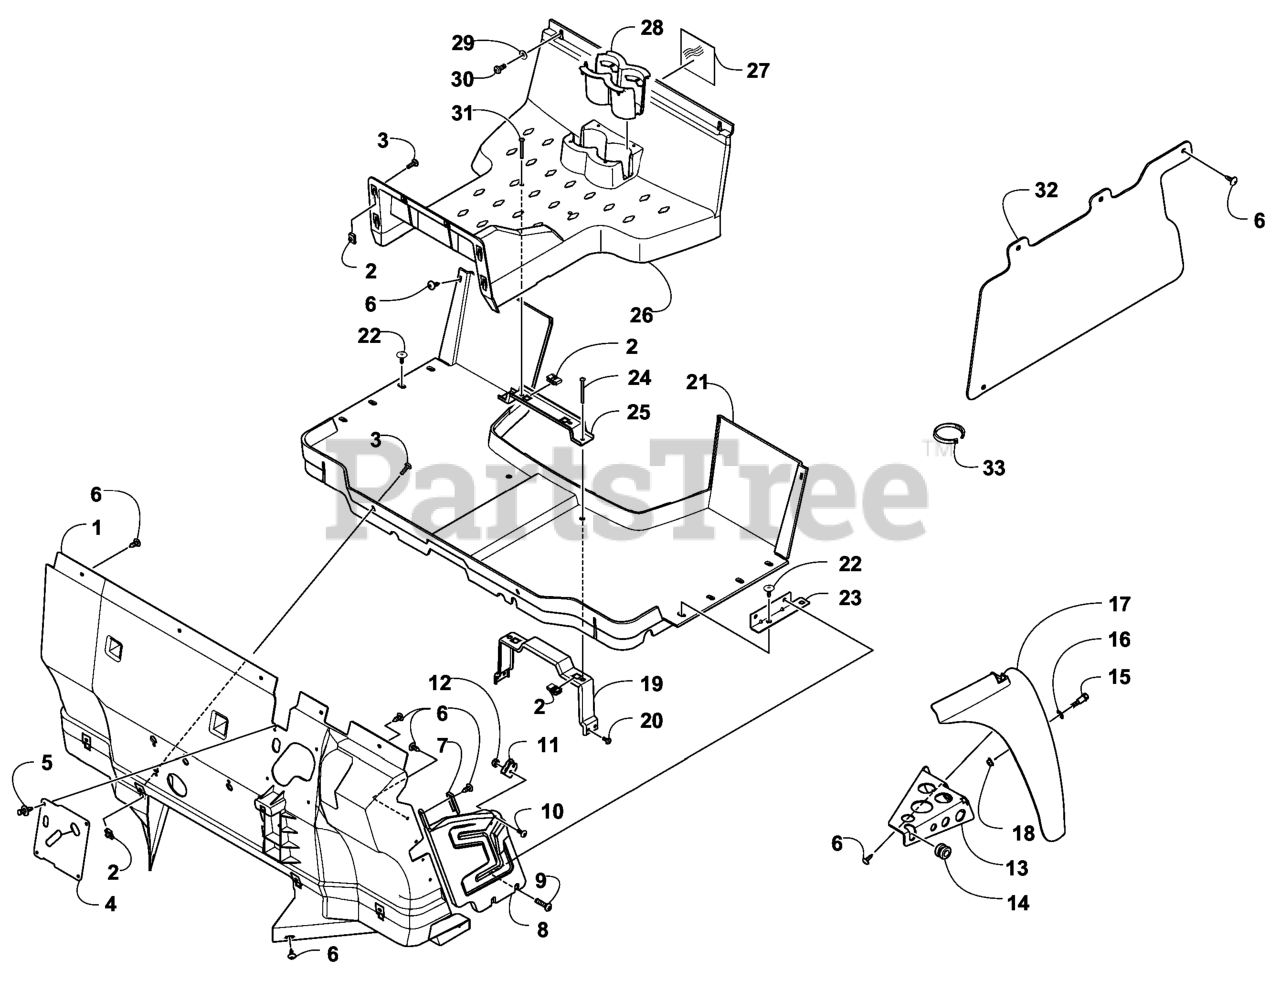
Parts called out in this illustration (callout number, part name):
1	PANEL-INNER FENDER
2	CLIP-U NUT
4	BOOT-STEERING
5	RIVET-PLASTIC, REINSTALLA
6	SCREW-TSTRH, SELFTAP
7	BRACKET-KICK PANEL
8	PANEL-SIDE KICK
9	SCREW-TSPNH
10	SCREW-TSPRH
11	TONGUE-BUCKLE
12	NUT-LOCK
13	BRACKET-SUPPORT, RH
13	BRACKET-SUPPORT, LH
14	GROMMET-GAUGE MOUNT
15	SCREW-HEX,DOME HEAD SHLDR
16	WASHER-FLAT
17	FENDER-FRONT, RH
17	FENDER-FRONT, LH
18	NUT-HHF,TOP LOCK
19	BRACKET-SUPPORT, FLOOR
20	SCREW-TSPRH
22	SCREW-SELF TAP
23	BRACKET-KICK PANEL, RH
23	BRACKET-KICK PANEL, LH
25	BRACKET-MOUNT, SUBFLOOR
26	FLOOR-SUB/SHIELD ASM
27	SHIELD-SUB FLOOR
28	GROMMET-CUPHOLDER
29	WASHER-FLAT
31	SCREW-TSPNH
32	PANEL-SPLASH, REAR
33	TIE-CABLE
